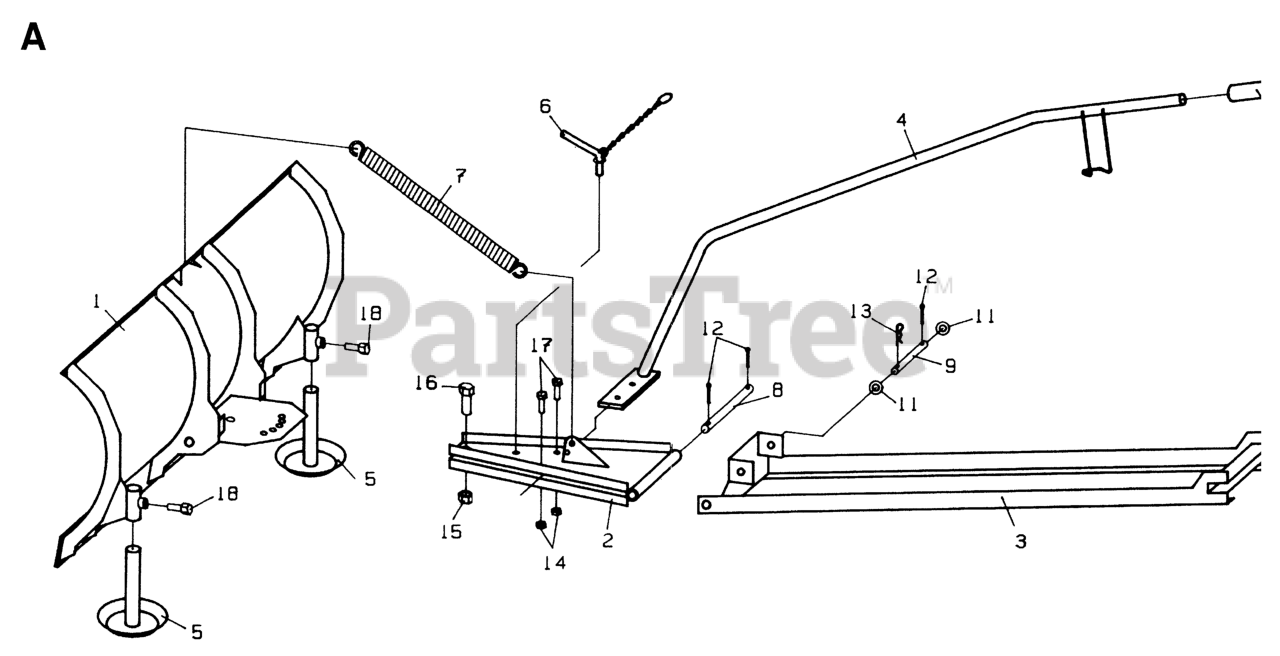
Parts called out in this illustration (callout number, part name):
6	LIFTING ARM LINK
21	CONNECTION ROD
24	RETAINING RING
25	CONNECTION ROD
29	WASHER BRB 8.4X17
30	LOCKNUT M8
